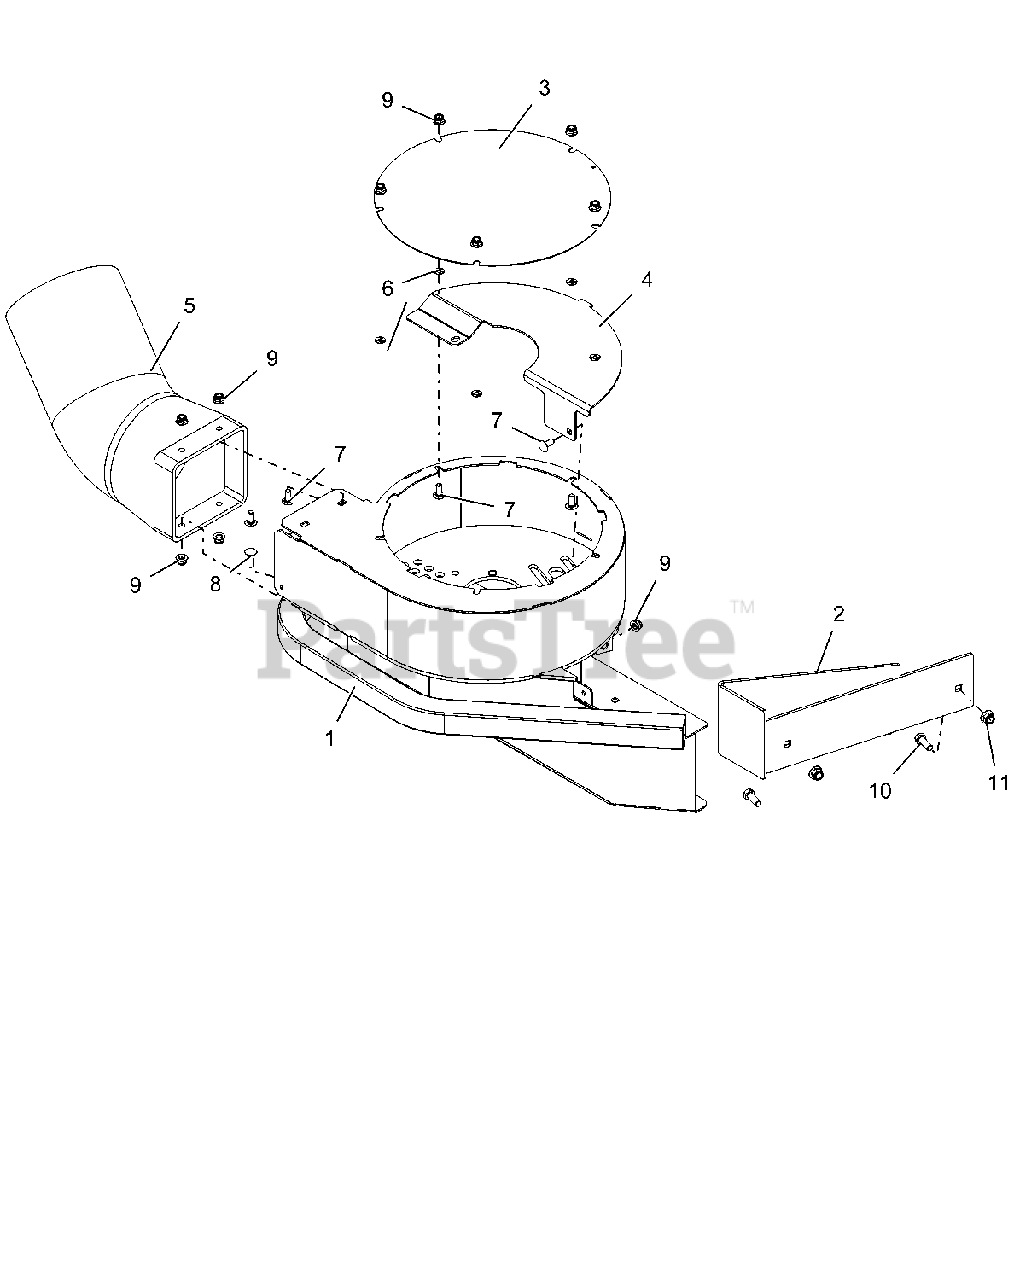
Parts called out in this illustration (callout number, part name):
1	WLDMT, COMM BAGGER BLOWER - RED
2	WLDMT, 72" BAGGER BAFFLE
3	COVER, BLOWER -BLACK
4	COVER, BOTTOM - BLK
5	ADAPTOR, HOSE
6	NUT, PUSH .312
7	BLT-RHDSSQNK .31-18X.75 G5YZ
8	BLT-RDHDSQSHNK .31-18X1.00 G5YWZC
9	NUT-LK-NYL-FLG .31-18 YWZC
10	BLT-HEX .38-16X1.00 GR5 YWZC
11	NUT-LK-NYL-FLG .38-16 YWZC
